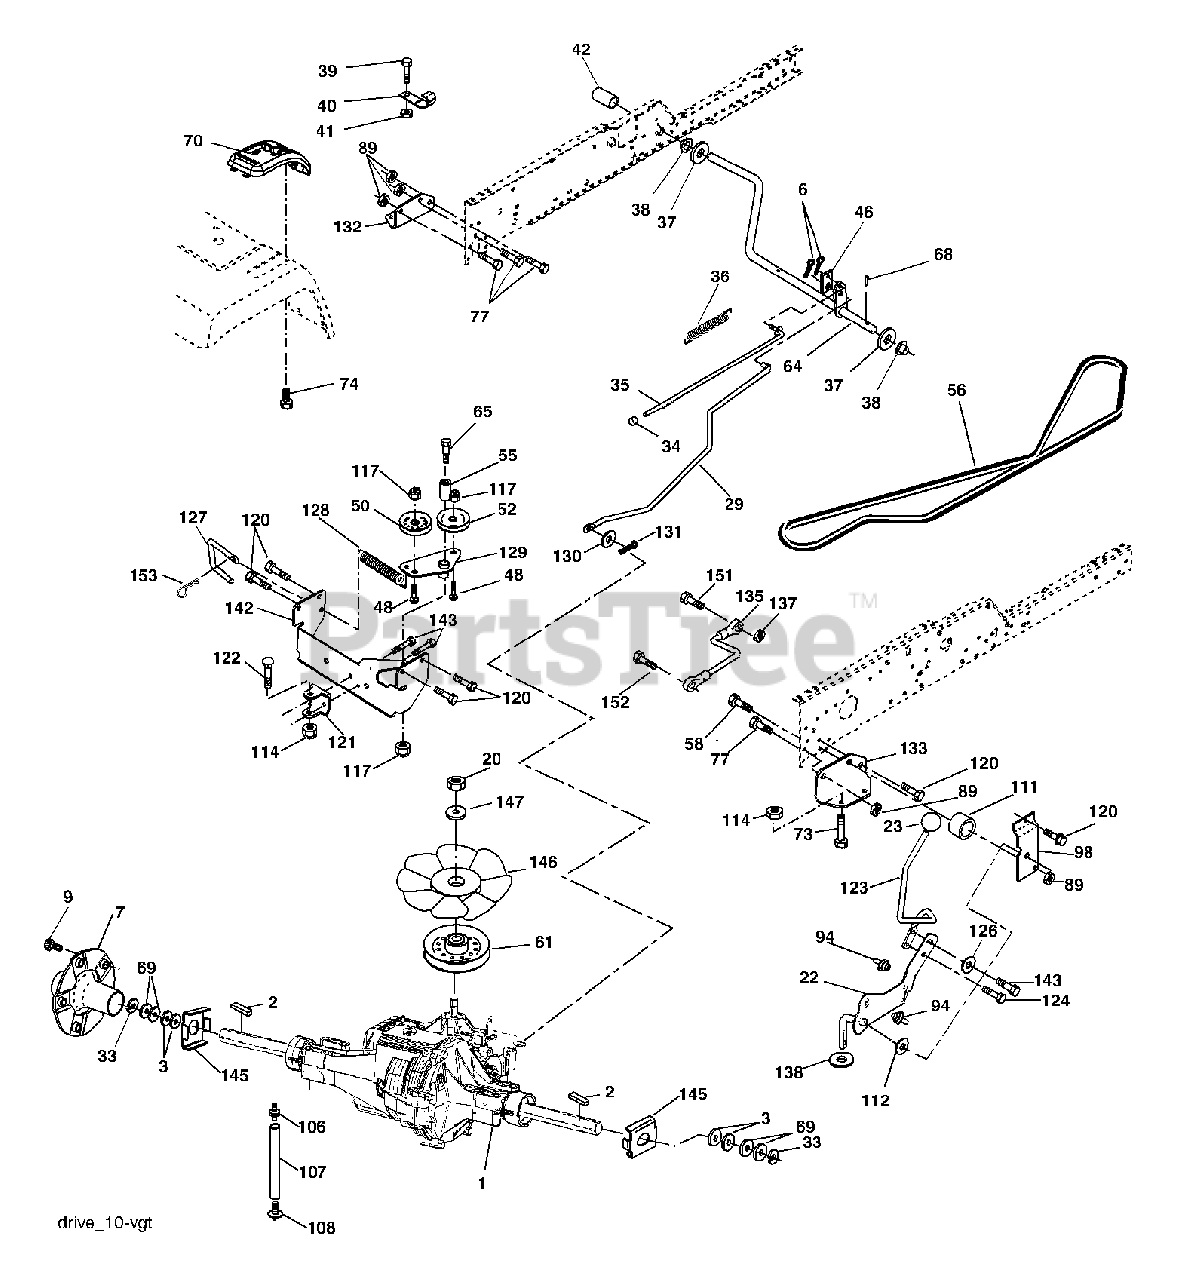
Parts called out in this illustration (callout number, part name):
2	Key Sq. 1/4 x 1/4 x 2.5
3	Washer Thrust
6	Pin, Cotter
7	Wheel, Hub Assembly
22	Lever Asm Shift
29	Brake, Rod
34	Cap, Parking Brake
35	Rod, Parking Brake
36	Spring, Drive Ground
37	Washer 25/32 x 1-1/4 x 16 Ga.
39	Screw, Fin. #10-24 x 1
40	Actuator, Interlock VGT
41	Nut Centerlock 10-24 unc
42	Cover, Pedal
46	Retainer, Spring
48	Bolt Rdhd 3/8-16 x 1.3/4 Gr. 5
50	Pulley, Idler, Flat
52	Pulley, Idler, Grooved
55	Bearing, Idler
58	Bolt Fin Hex 7/16-14 x 1-1/2
61	Pulley, Transaxle
64	Shaft, Brake Pedal
65	Bolt, Shoulder
70	Console Automatic YT/GT
73	Bolt Hex Flghd 5/16-18 x 3 Gr. 5
74	Screw Hex Wsh. Hi-Lo 1/4-1/2
77	Bolt Fin Hex 7/16-14 x 1
89	Nut Crownlock 7/16-14 unc
94	Fastener Christmas Tree
98	Bracket Shift
106	O-Ring Asm Hydro Gear
107	Line Fuel Hydro 15" VGT
108	Cap Asm Vent Hydro Gear
111	Spacer Shift Lever VGTH
112	Washer Nylon High Temp
114	Nut Lock Hex W/lns 5/16-18 unc
117	Nut, Lock Flg. 3/8-16
120	Screw 318-16 x .75
121	Bracket Strap Torque
122	Bolt RDHDSQ 5/16-18 un x 2-1/2
124	Bolt Shoulder 5/16-18 x .561
126	Washer SRRTD 5/16 ID x 1.O x .125
127	Link Control Clutch
128	Spring Drive GRND
129	Bracket Asm Idler Tensioning
130	Washer 13/32 x 5/8 x 16 Ga.
131	Pin Cotter 3/32 x 3/4
132	Bracket Mtg Hydro 3500 LH VGT
133	Bracket Mtg Hydro 3500 RH VGT
135	Link Asm Control Hydro 3500
137	Nut Lock 5/16-18 NC Thd.
138	Washer Thrust 5/8 x 1.10 x 1/32
142	Strap Torque HG-3500
143	Screw Thdrol 5/16-18 x 3/4
145	Washer Axle Flange HG-3000
146	Fan 7" Hydro
151	Bolt Hex 5/16-18 x 7/8
152	Bolt Hex 5/16 x 1 W/Patch
153	Spring, Retainer
